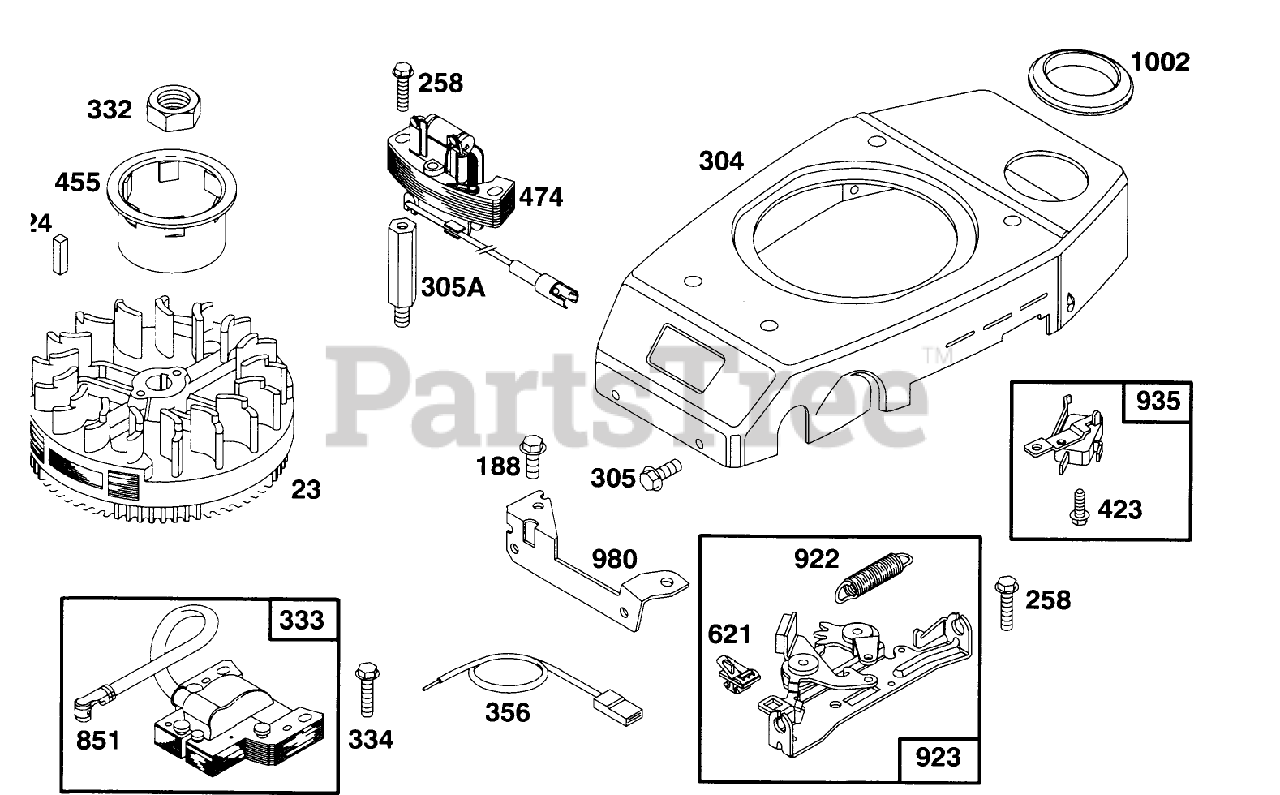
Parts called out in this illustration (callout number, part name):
23	FLYWHEEL - MAGNETO
24	KEY - FLYWHEEL
305	SCREW - HEX HEAD
332	NUT - HEXAGON
334	SCREW - SEM
356	WIRE - GROUND
621	STOP SWITCH
980	BRACKET-BLOWER HSG
